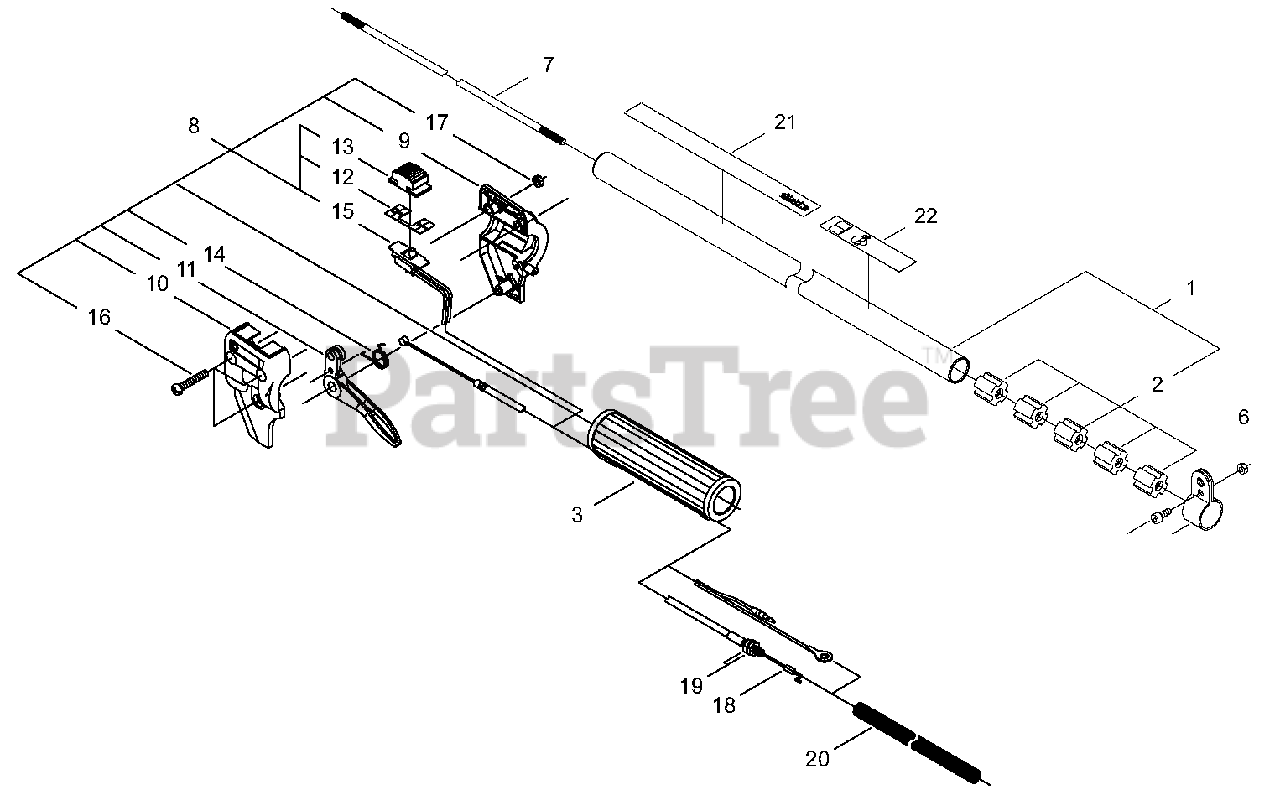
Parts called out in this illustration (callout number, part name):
1	MAIN PIPE ASSY
2	BUSHING
3	GRIP - REAR
4	BRACKET
5	SCREW - 5X12
6	NUT - 5
7	DRIVESHAFT - SOLID
8	THROTTLE CONTROL KIT
9	BRACKET - RIGHT
10	BRACKET - LEFT
11	TRIGGER, THROTTLE
12	PLATE, SWITCH
13	KNOB
14	SPRING
15	SWITCH, IGNITION
16	SCREW - 5X30
17	NUT - 5
18	CABLE, THROTTLE
19	NUT - 6
20	TUBE
21	LABEL - SHINDAIWA PROFESSIONAL
22	LABEL - CAUTION
